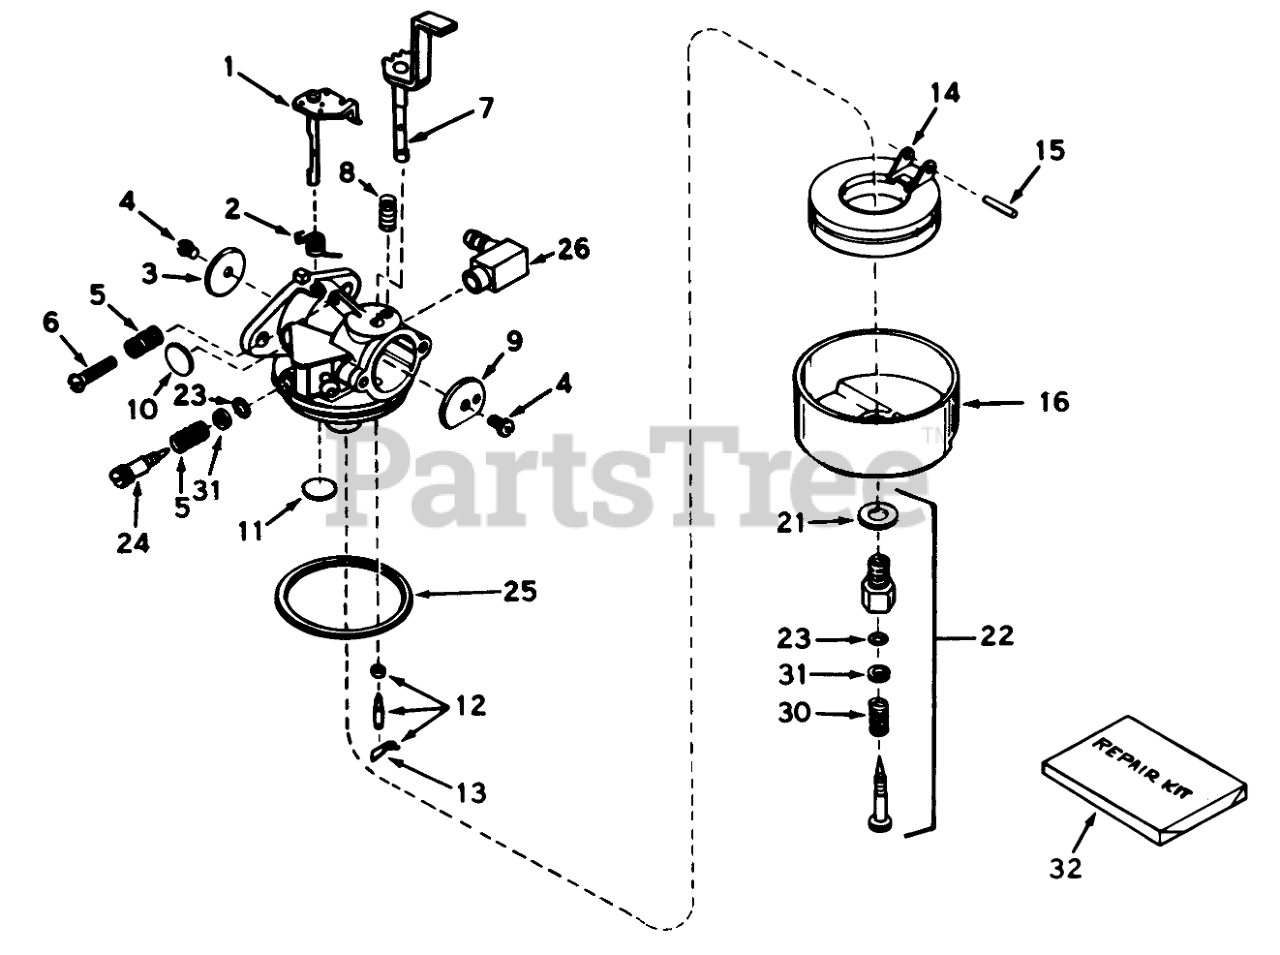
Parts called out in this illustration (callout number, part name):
1	Throttle Shaft and Lever ASM
2	Spring, Throtte Return
3	Shutter-Throttle
4	Screw-Shutter
5	Spring-Tension
6	Screw-Throttle Crack Screw / Idle Speed
7	Shaft & Lever Assy., Choke
8	Spring-Positioning, Choke
9	Shutter-choke
10	Plug-Welch, Idle Mixture Well
11	Plug-Welch, Atmospheric Vent
12	Inlet Needle, Seat & Clip Assy. (Incl. #13)
13	Clip-Spring
14	Float
15	Shaft-Float
16	Bowl-Float (no drain)
21	Washer-Bowl Nut
22	Adjustment Screw Assy., Main (Incl. #21, 23, 30 & 31)
23	"O"Ring
24	Screw, Idle Adj.
25	O Ring-Bowl, Float
26	Fitting-Fuel
32	Kit-Repair
